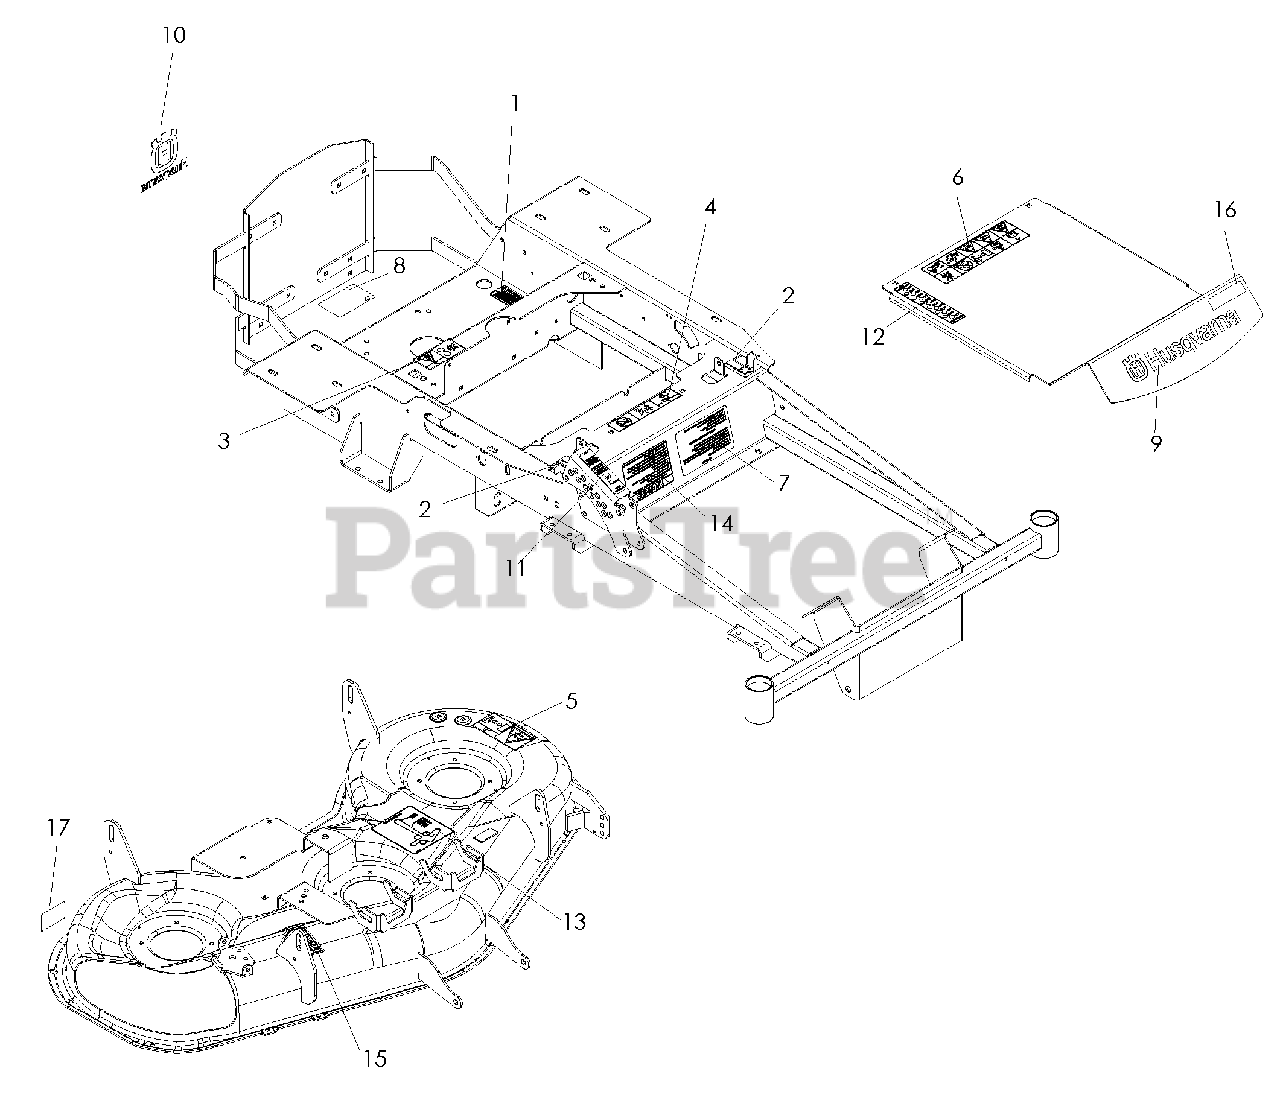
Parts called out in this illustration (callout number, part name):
1	DECAL, PROP 65
2	DECAL, MOTION CONTROL
3	DECAL, EURO DNGR BELT
4	DECAL, EURO BATT WARN
5	DECAL, EURO SEVERING
6	DECAL, WARNING
7	DECAL, START
8	DECAL, DO NOT TOW
9	DECAL, HUSQVARNA
10	DECAL, CROWN
11	DECAL, TRANSPORT REL
12	DECAL, HEIGHT ADJUST
13	DECAL, BELT ROUTING,
14	DECAL, WARNING
15	DECAL, WARNING
16	DECAL, EZ4624
17	DECAL, WARNING
